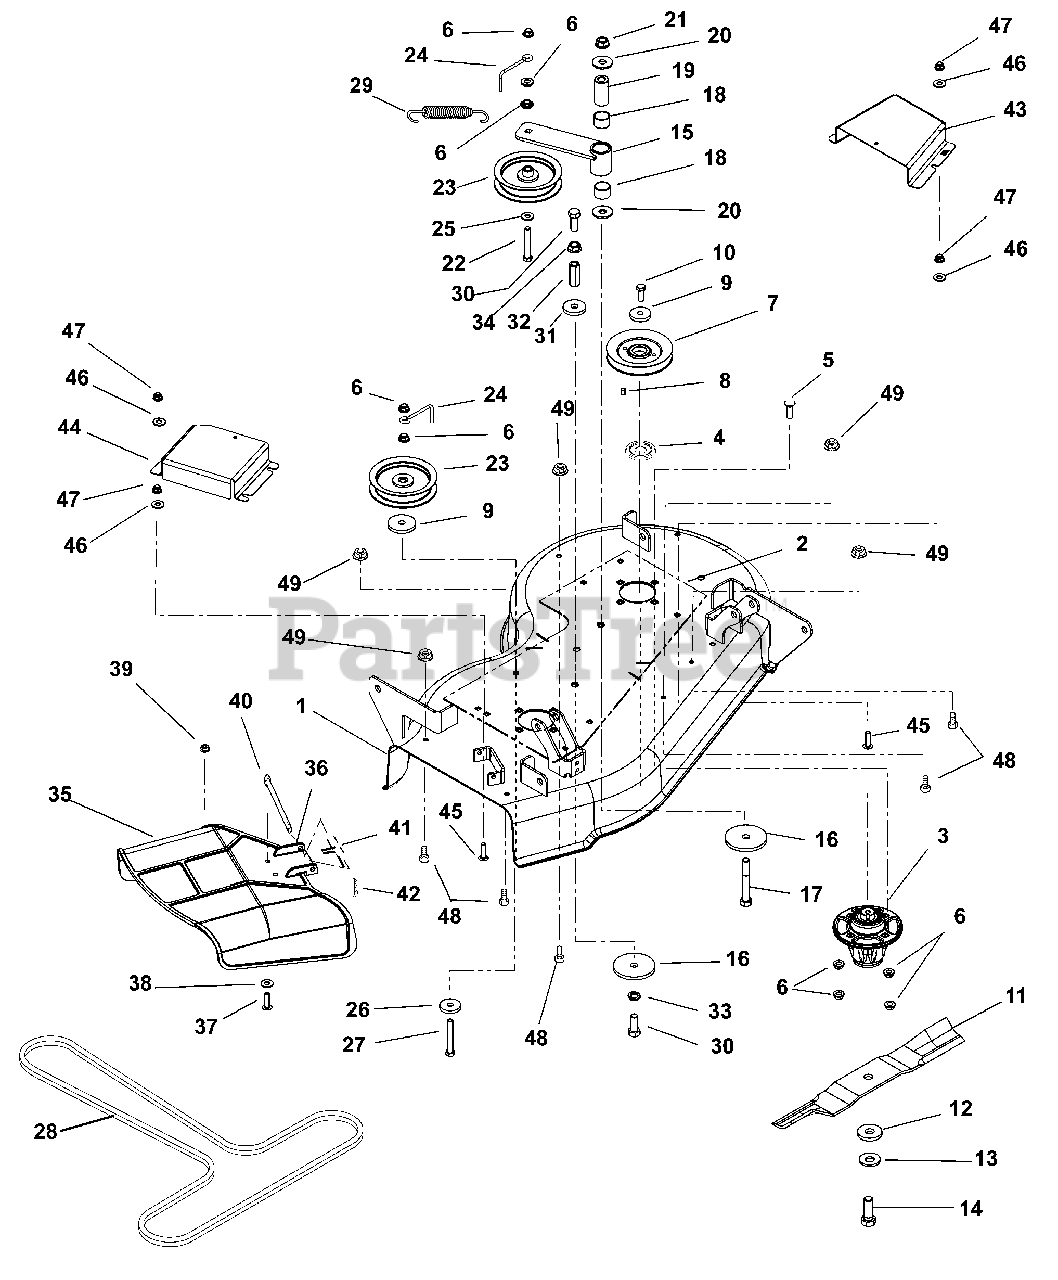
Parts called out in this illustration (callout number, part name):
1	34" Deck, Stamped
2	Doubler Plate, 34" Deck
3	Spindle Assembly
4	Dust Cap
5	Bolt, Round Head Square Neck .38-16 x 1.25 Grade 5
6	Nut, .38-16 Nyloc Flange
7	Sheave, 4.75 Diameter A-Section
8	Key, Square .25 x .38 x
9	Washer, Flat Steel .406 x 1.50 x .245
10	Bolt, Hex .38-16 x 1.00 EP30
11	Blade, 17.5 x 2.25 x .197
12	Washer, Flat .640 x 1.81 x .250
13	Washer, Bellville .63 x 1.625 x .14
14	Bolt, Hex .62-18 x 1.75 Grade 8
15	Idler Arm
16	Washer, Flat-Steel .515 x 1.625 x .250 YZ
17	Bolt-Hex .50-13 x 3.50 Grade 5
18	Bearing, 1.00 x 1.12 x .75
19	Bushing, Spacer .505/.500 x .999/.996 x 2.05/2.03 Promaster
20	Washer, Flat-Steel .511 x 1.441 x .125
21	Nut, Locking-Top-Flange .50-13
22	Bolt, Hex .38-16 x 2.50 Grade 5
23	Idler, Flat .38 x 4.00 x 1.06
24	Belt Finger
25	Bushing, Flange .406 x .88 x .270 x .140
26	Washer, Flat-Steel .469 x 2.00 x .25
27	Bolt, Hex .38-16 x 2.75 Grade 5
28	Belt, HA 98.75 Wrapped
29	Extension Spring
30	Bolt, Hex .50-13 x 1.25 Grade 5
31	Washer, Flat-Steel .515 x 1.625 x .250 YZ
32	Nut, Coupling .50-13 x 1.75
33	Washer-Locking .50 x .125 Regular
34	Nut, Spin Lock-Flange .50-13
35	Molded Chute, Zoom
36	Chute Reinforcement
37	Screw, Socket Head .31-18 x .75 Button Head
38	Washer, Flat-Steel .38 x .875 x .083
39	Nut, Locking-Top-Flange .31-18
40	Clevis Pin, 5/16 x 4.0
41	Spring, Torsion
42	Pin, Hair Internal .08 x .18 x 1.18
43	Belt Cover, 34" Left
44	Belt Cover, Right 34"
45	Bolt, Round Head Square Neck .31-18 x 1.25 Grade 5
46	Washer, Flat-Steel .38 x .875 x .083
47	Nut, .31-18 Nyloc Flange
48	Bolt, Hex .31-18 x .75 Grade 5
49	Nut, Spin Lock Flange .312-18
